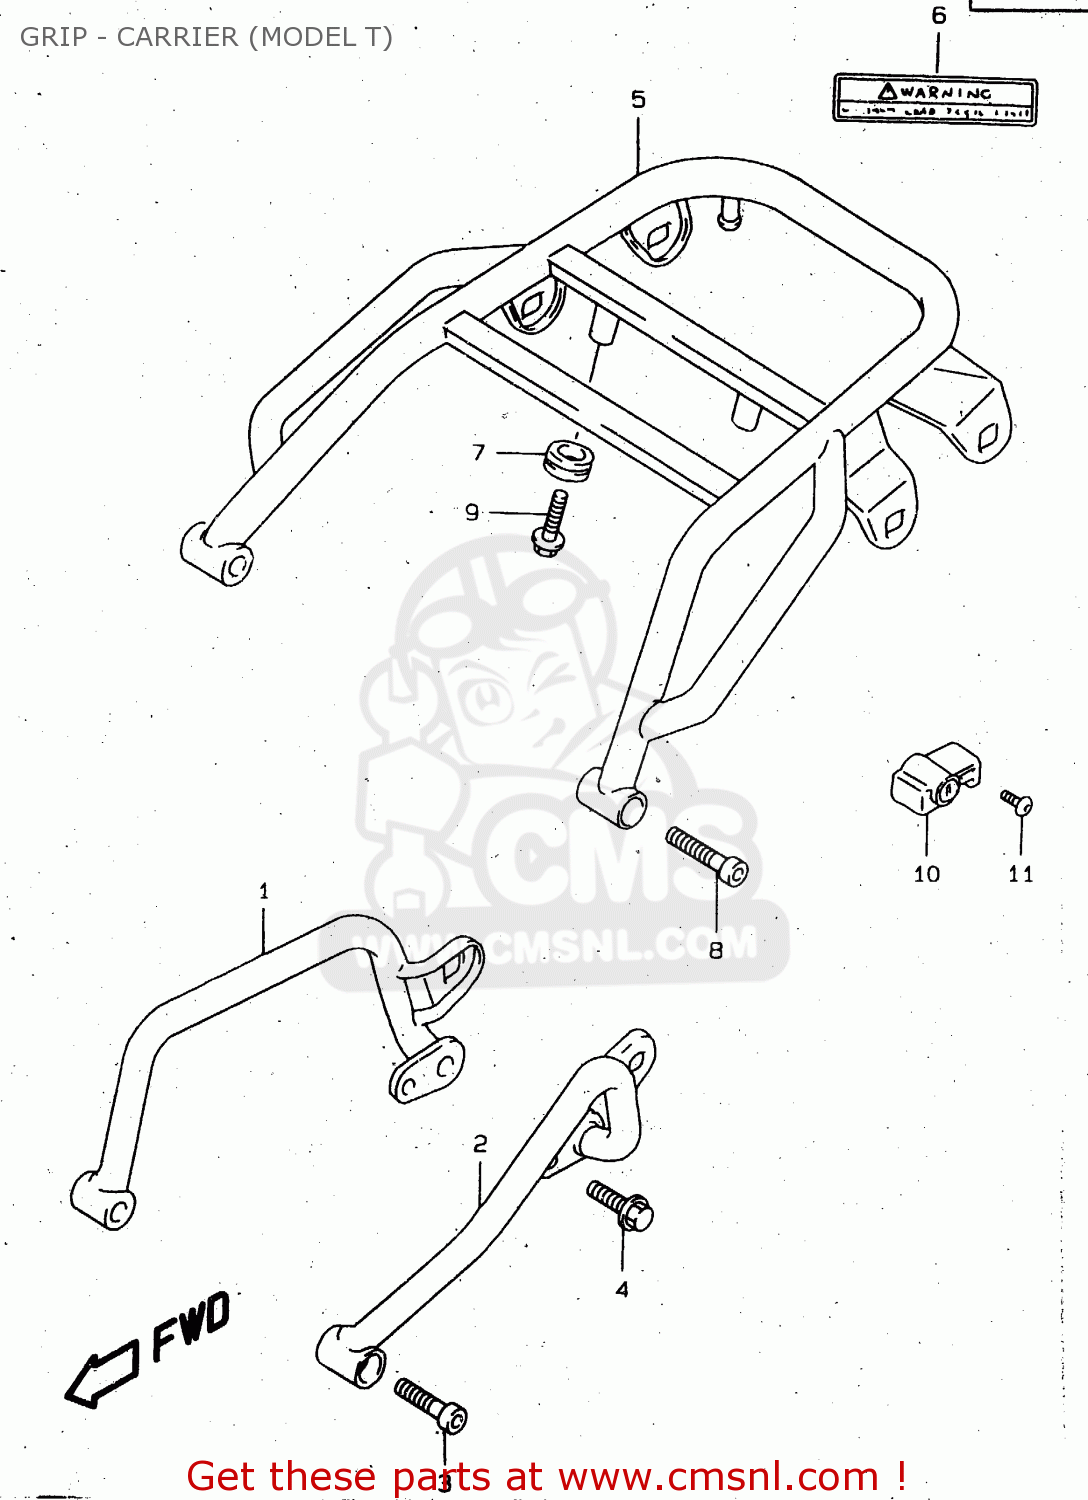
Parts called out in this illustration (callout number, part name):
1	GRIP,RR,R
2	GRIP,RR,L
3	BOLT
4	BOLT
5	DR650 REAR RACK
6	LABEL,WARNING RR CARRIER
7	GROMMET
8	BOLT
9	BOLT
10	LOCK SET,HELMET
11	SCREW(6X14)
